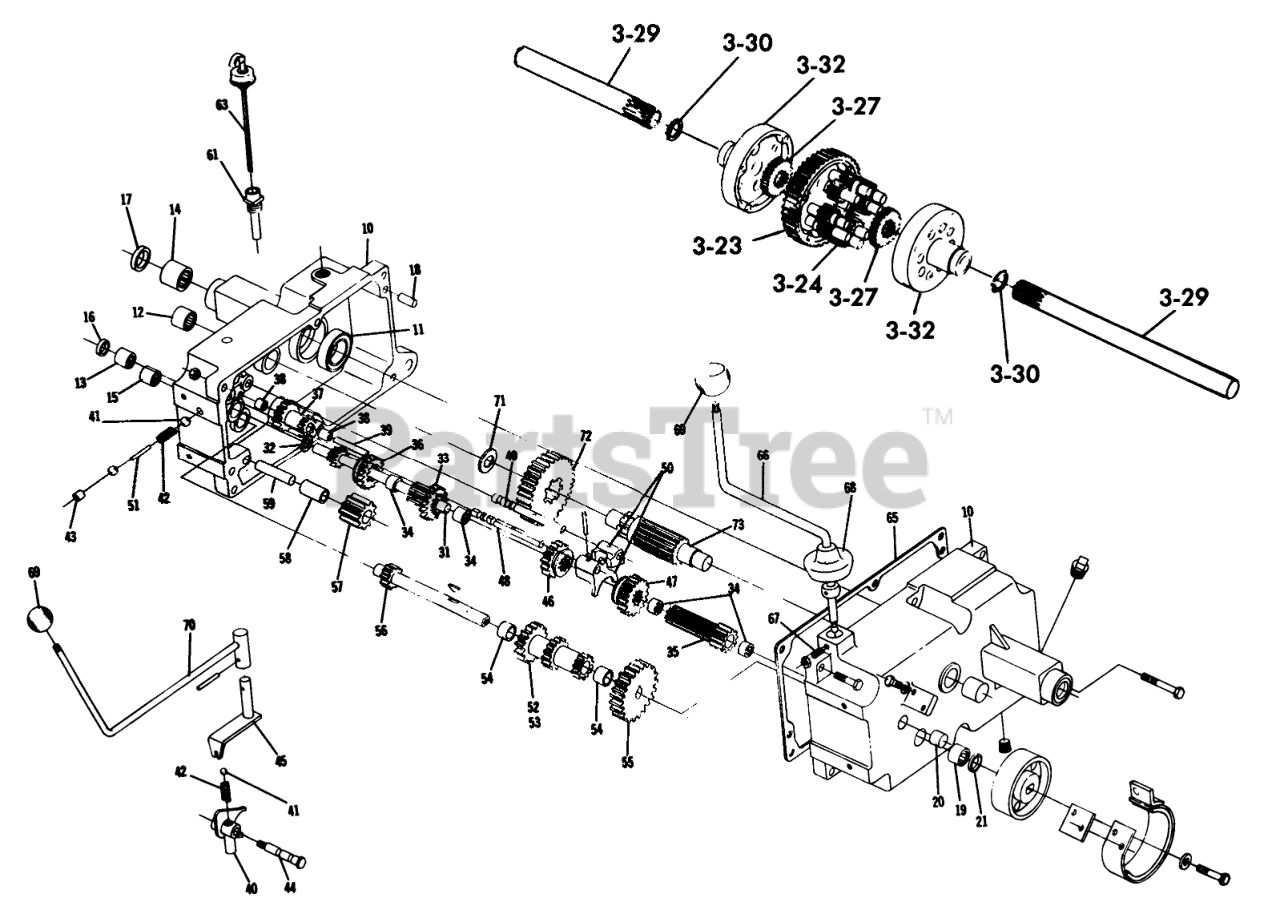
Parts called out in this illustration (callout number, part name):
3-23	GEAR-DIFFERENTIAL RING, 43T
3-24	GEAR-PINION, 11T
3-27	GEAR-AXLE DIFFERENTIAL
3-32	WASHER-THRUST
12	BEARING-NEEDLE
13	BEARING-NEEDLE
15	BEARING-NEEDLE
16	SEAL-OIL
17	SEAL-OIL
18	PIN-DOWEL
19	BEARING-NEEDLE
21	SEAL-OIL
22	DIFFERENTIAL END CAP
31	SHAFT-INPUT
33	GEAR
34	BEARING-NEEDLE
35	GEAR
36	GEAR-SLIDING
38	BEARING-NEEDLE
39	GEAR-SHAFT REDUCTION
41	BALL-DETENT
43	CUP-PLUG
44	BOLT-DETENT
45	SHIFT ASM
46	GEAR-HI AND 2ND
47	GEAR-LOW AND REVERSE
48	RAIL-SHIFT
49	RAIL-REAR SHIFT
50	FORK-SHIFT
51	PIN-SHIFT
52	GEAR-CLUSTER
54	BUSHING-BRONZE
55	GEAR-CLUSTER SHAFT
57	GEAR/BUSHING ASM-REVERSE IDLER
58	BUSHING
59	PIN-DIFFERENTIAL
65	GASKET-TRANSMISSION
67	SETSCREW
68	COVER-DUST
69	SHIFT KNOB
71	WASHER-THRUST
72	GEAR ASM
73	PINION SHAFT
